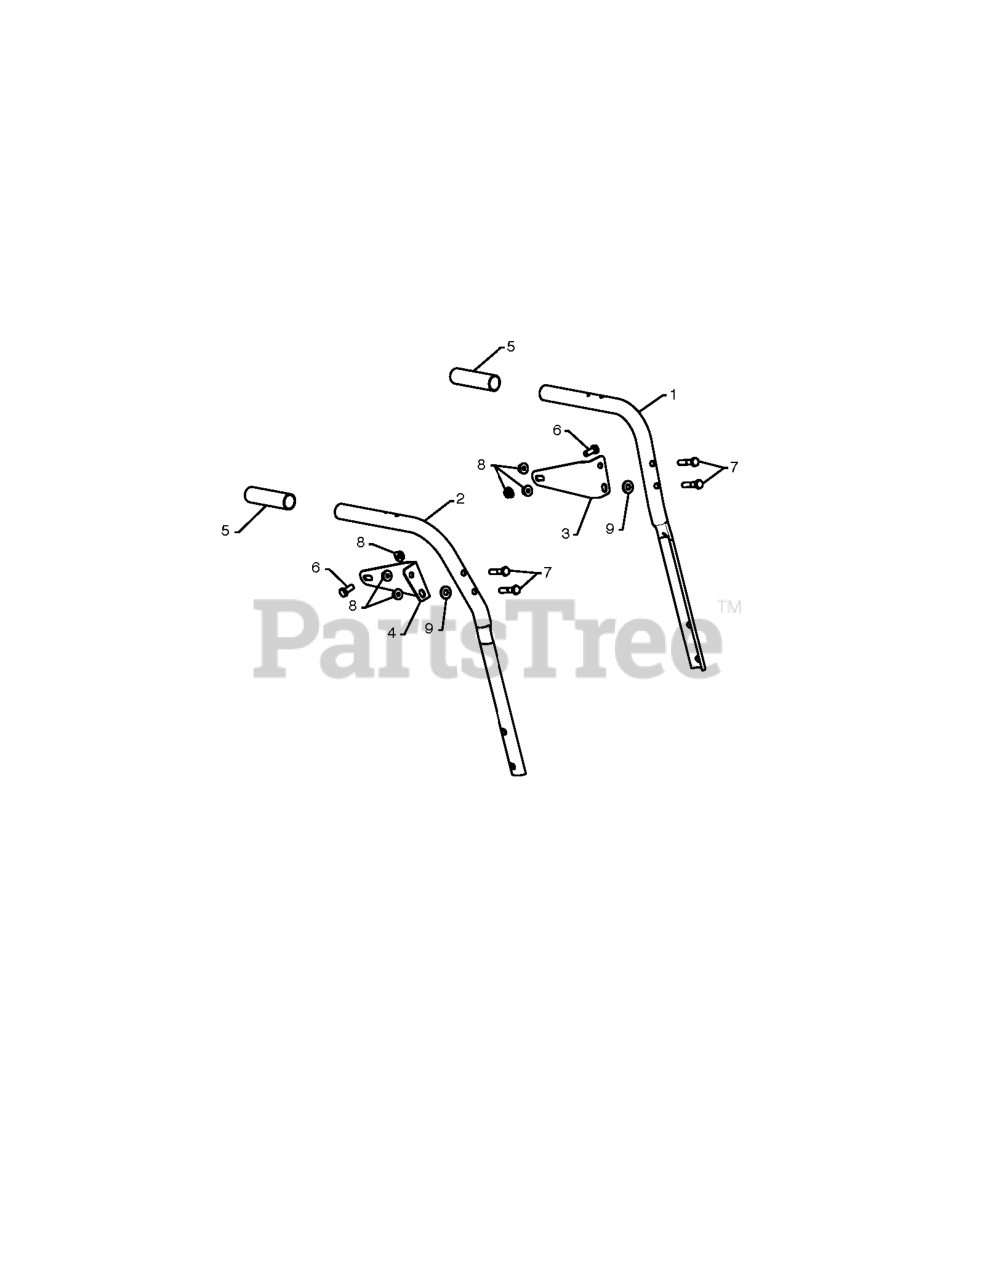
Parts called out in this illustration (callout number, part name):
1	TUBE.HANDLE.PLOW.LH.GREY
2	TUBE.HANDLE.PLOW.RH.GREY
3	BRKT.PANEL.LH.INT
4	BRKT.PANEL.RH.INT
5	GRIP, HANDLE
6	BOLT.FIN.HEX.5/16-18X3/4
7	HEX BOLT
8	NUT.LOCK.5/16-18
9	WASHER.20X8.5
